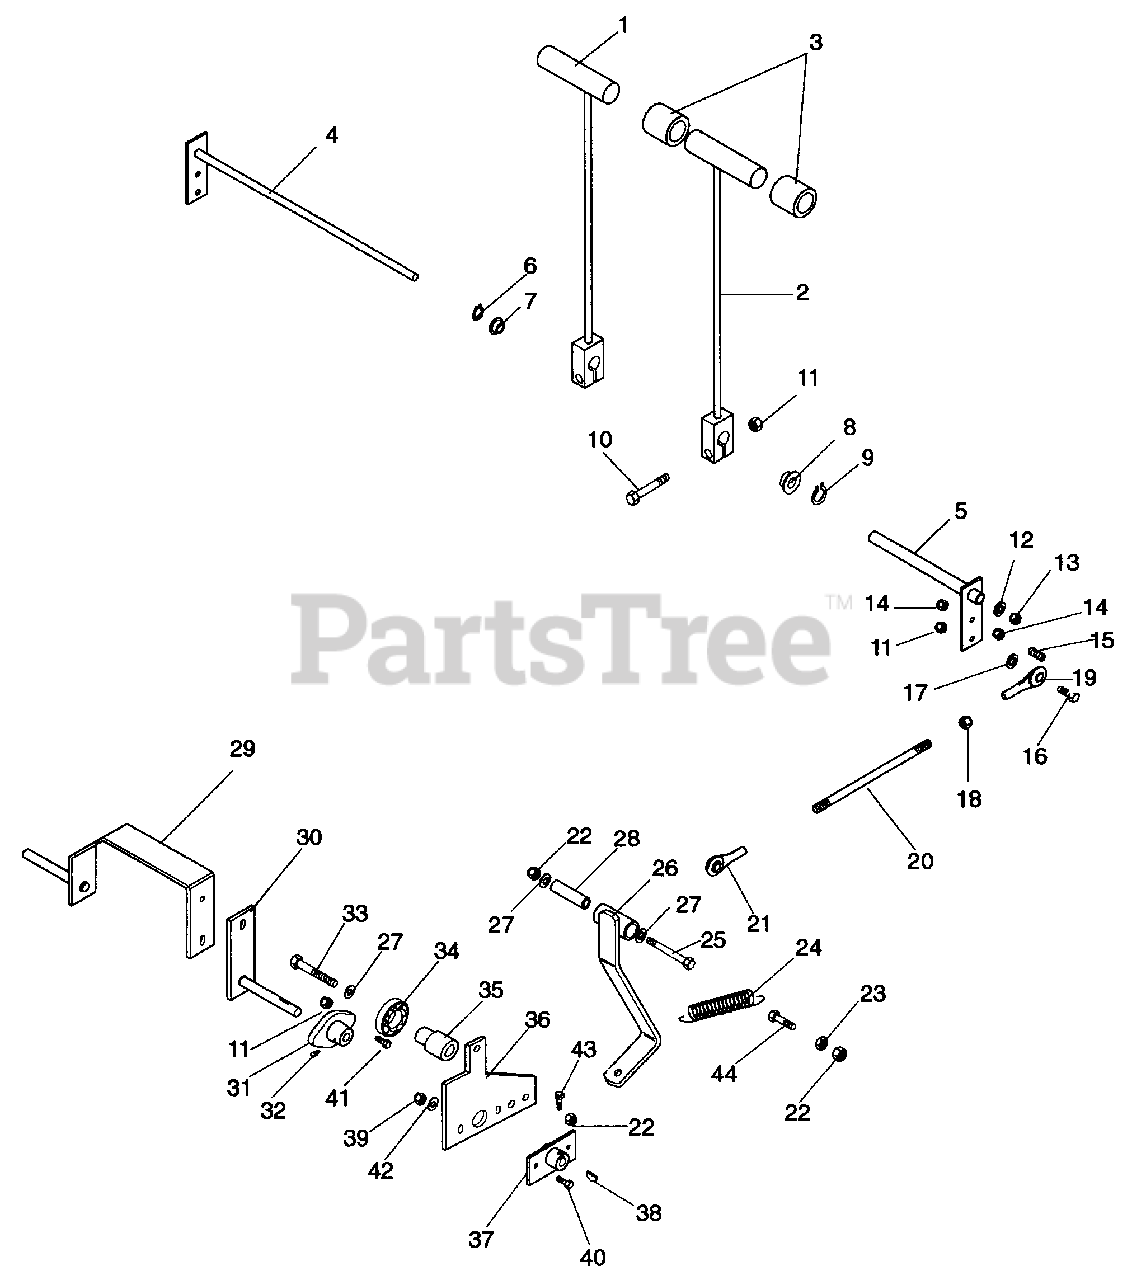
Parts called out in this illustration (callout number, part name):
1	WLDMT, STEERING LEVER L.H.
2	WLDMT, STEERING LEVER R.H.
3	GRIP, T-BAR
4	WLDM'T, STEERING ROD
5	WLDMT, STEERING TUBE
6	RG, RETAINING
7	BUSH, F .515 X 1.00 X .745 NY
8	BSHG-FLG .762 X 1.0 X .580 X 1.48 NY
9	RG-RTNG-EXT .689 X .077
10	BLT-HEX .31 - 18 X 1.50 PL GR 5
11	NUT-LK-NYL .312 - 18 PL
12	WSHR-FL-STL .531 X 1.062 X .095
13	NUT-LK-NYL .50 - 13 PL
14	NUT HEX .312 - 18
15	SCR-SET .32-18 X 1.50 SKHCUP
16	BLT-HEX .31-18 X 1.25 PL GR 2
17	WSHR-FL-STL .344 X .688 X .065 PL
18	Nut - 5/16-24, Hex, Plated
19	ROD END, 5/16" FEMALE
20	ROD, STEERING ADJ
21	ROD END, 5/16 - 24 LH FEMALE
22	NUT-LK-NYL .375-16 PL
23	NUT-HEX .375 - 16
24	SPRG, EXT LE - 063F-5
25	BLT-HEX .38 - 16 X 2.75 PL GR 5
26	WLDMT, NEUTRAL DETENT
27	WSHR-FL-STL .406 X .812 X .065 PL
28	BUSH., S .385 X .610 X 1.80 ST
29	WLDMT, PUMP CONTROL R.H.
30	WLDMT, PUMP CONTROL L.H.
31	BUSH., FLANGED SUPPORT
32	FTG, LUBE;, 25 - 28 SELF-THREAD
33	BLT-HEX .38 - 16 X 2.00 PL GR 5
34	BRG-BALL .500 X 1.375 X .437
35	HUB, BRG. MOUNT
36	ARM-SPEED CONTROL
37	WLDMT, NEUTRAL ADJ
38	KEY, WOODRUFF 1/8 X 3/4
39	NUT-LK-NYL .250 - 20 PL
40	BLT-HEX .25 - 20 X .75 PL GRS
41	BLT, HEX .31-18 X 1.00 PL GR 5
42	WSHR-FL-STL .281 X .62 X .065 PL
43	BOLT HEX 1/4 - 20 X .50
44	BLT-HEX .38 - 16 X 1.125
